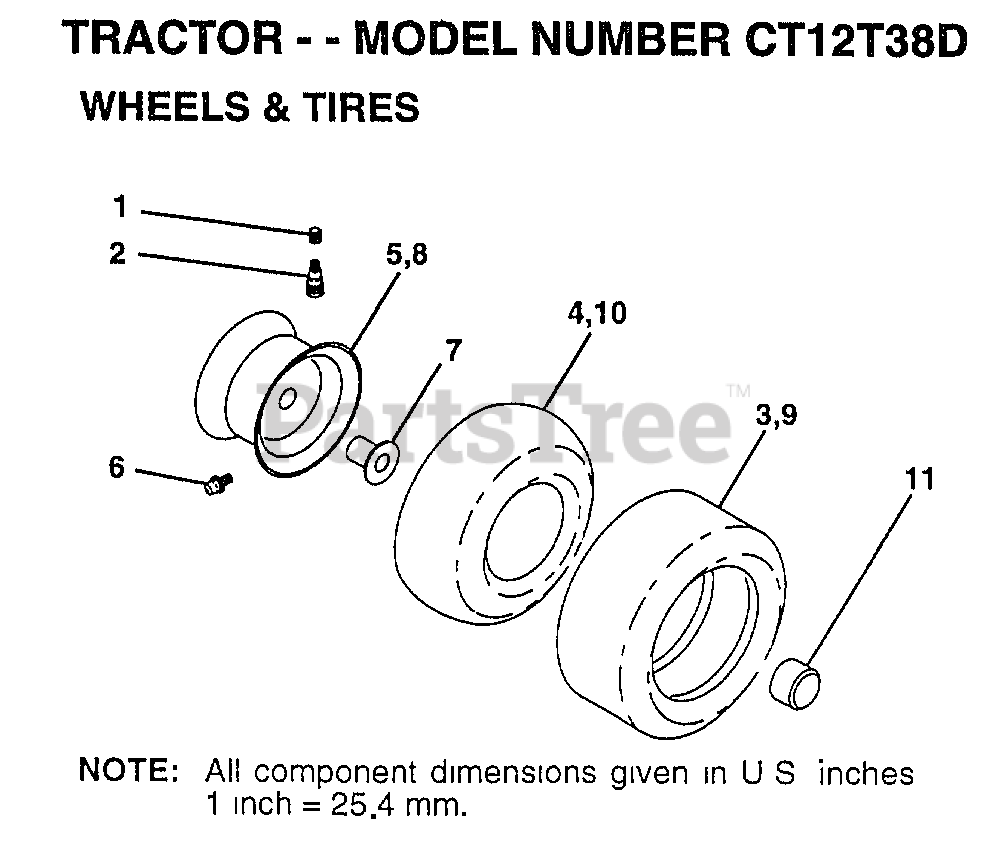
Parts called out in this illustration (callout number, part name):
1	VALVE CAP
2	VALVE STEM LT
4	TUBE.5.3/4.5/6
5	"RIM ASM 6"" FRT"
6	FITTING LT
7	"FLANGE, BEARING"
8	"RIM AS 8"" REAR"
9	TIRE.TS2.18X8.5
10	TUBE.18X9.5-8
11	HUB CAP
